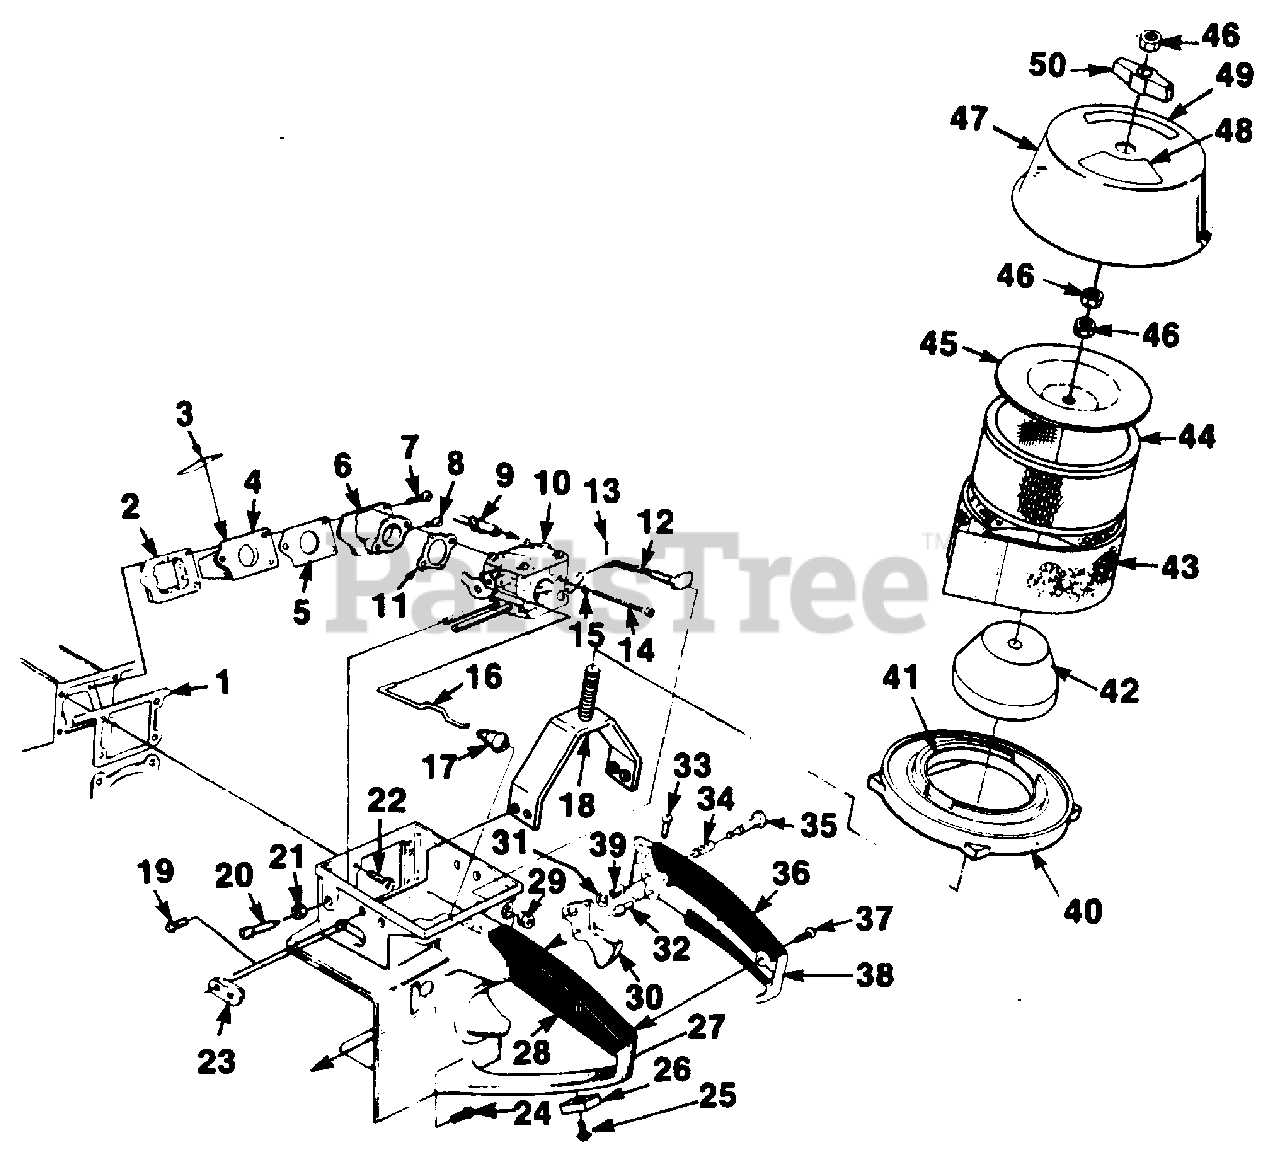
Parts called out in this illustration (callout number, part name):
2	RETAINER- Reed
3	REED- Valve
4	SEAT- Reed Valve
6	SPACER-Carburetor
7	SCREW- (8-32 x 1 1/4")
8	SCREW- Pan hd. (8-32 x 1")
9	FUEL LINE
10	CARBURETOR
12	CHOKE ROD
13	COTTER PIN
14	SCREW- (10-32 x 1 7/8")
15	WASHER- Lock (#10)
16	ROD- Throttle
17	BOOT-Throttle rod
18	BRACKET- Cover
20	SCREW- Idle Adjustment
21	NUT-Jam (5/16-24)
22	SCREW- Hex hd. (12-24 x 5/8")
23	GROMMET
24	SCREW- Hex hd. (12-24 x 7/8")
25	SCREW- (10-24 x 1/2")
26	PAD- Wear
27	HANDLE- Throttle
28	GRIP- Throttle handle
29	GROMMET
30	TRIGGER
31	RING- Retaining
33	SCREW- (8-32 x 5/8")
34	SPRING- Throttle lock
35	PIN- Throttle
36	GRIP- Throttle handle
37	SCREW- Pan hd. (8-32 x 1/2")
38	COVER- Throttle handle
39	BUSHING
40	RING & GASKET ASSY.
42	FILTER- Air
43	PRE FILTER- Felt
44	ELEMENT- Air filter
45	COVER- Filter Element
46	NUT- Hex (5/16-18)
47	AIR FILTER COVER
48	DECAL- Warning
49	DECAL- Instruction
50	KNOB- Handle
